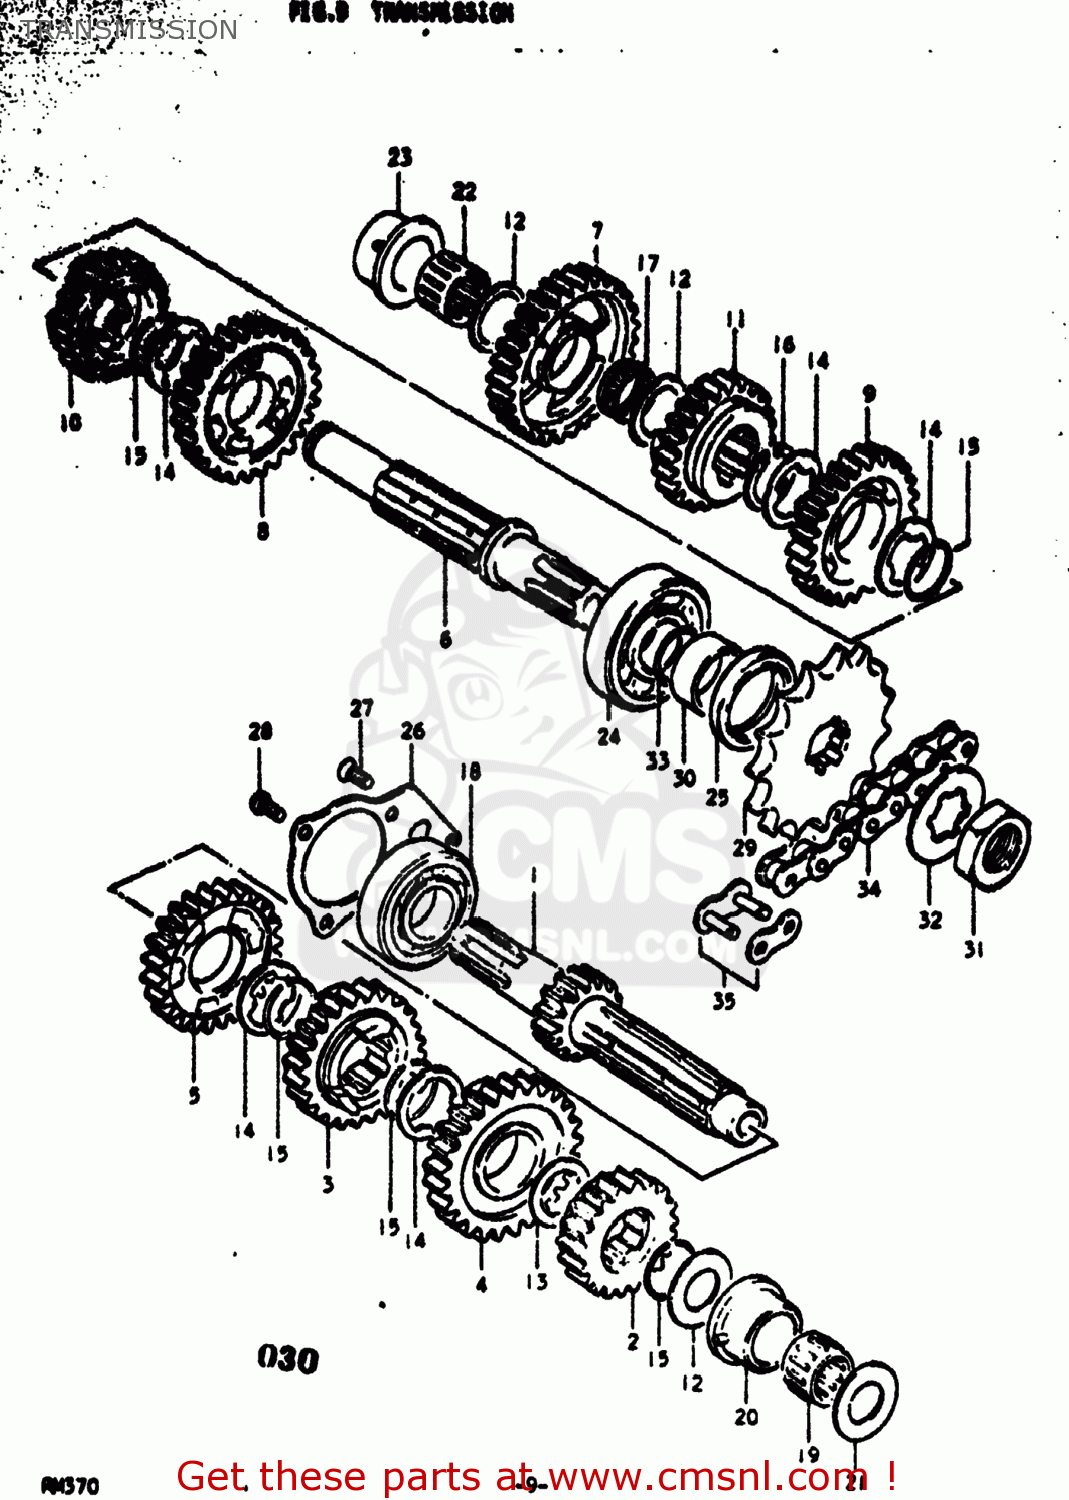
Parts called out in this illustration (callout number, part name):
1	SHAFT,COUNTER
2	GEAR,SECOND DRIVE
3	GEAR,THIRD DRIVE
4	GEAR,FOURTH DRIVE
5	GEAR,FIFTH DRIVE
6	SHAFT,DRIVE
7	GEAR,FIRST DRIVEN
8	GEAR,SECOND DRIVEN
9	GEAR,THIRD DRIVEN
10	GEAR,FOURTH DRIVEN
11	GEAR,FIFTH DRIVEN
12	WASHER (20X30X1)
13	WASHER
14	WASHER,LOCK
15	RING,SNAP
16	CIRCLIP
17	BEARING(20X24X10).8
18	BEARING
19	BEARING(20X24X16.8)
20	BUSHING
21	SPACER(20X28X13)
22	BEARING(20X24X16.8)
23	BUSHING
24	BEARING
25	SEAL,OIL(32X42X6)
26	PLATE,COUNTERSHAFT BEARING
27	SCREW
28	SCREW 6X12
29	SPROCKET,ENGINE
30	SPACER(22X32X11.5)
31	NUT
32	WASHER,LOCK
33	O RING(D:1.7,ID:22)
34	CHAIN ASSEMBLY,DRIVE
35	JOINT ASSEMBLY,CHAIN
